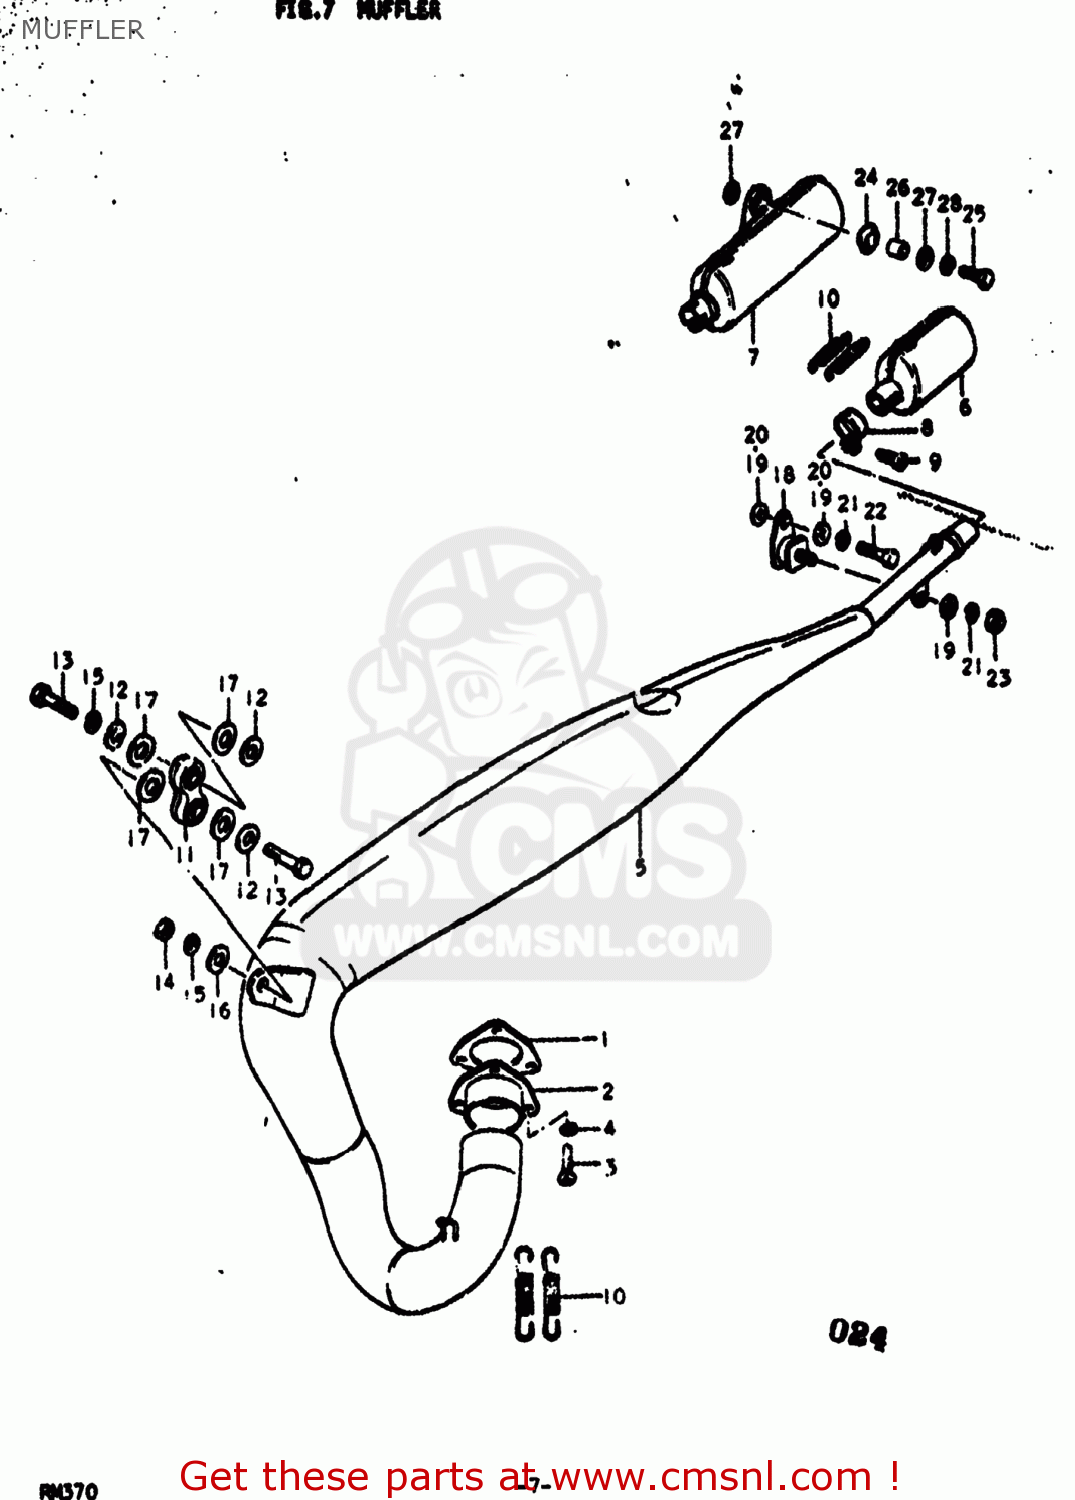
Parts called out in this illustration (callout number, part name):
1	GASKET,EXHAUST PIPE (MCA)
2	FLANGE,EXHAUST PIPE
3	SCREW
4	LOCK WASHER
5	BODY,MUFFLER
6	BODY,MUFFLER
7	BODY,MUFFLER
8	CLAMP
9	BOLT(6X20)
10	SPRING
11	DAMPER,MUFFLER
12	WASHER
13	** SUPERSEEDED
14	NUT
15	LOCK WASHER
16	WASHER
17	WASHER(13X28X1.6)
18	DAMPER,MUFFLER SUPPORT
19	WASHER
20	WASHER (8.2X20X1.6)
21	LOCK WASHER
22	BOLT
23	NUT
24	CONNECTOR,MUFFLER
25	BOLT
26	SPACER (6.5X10.5X11)
27	WASHER (6.5X24X1.6)
28	LOCK WASHER
